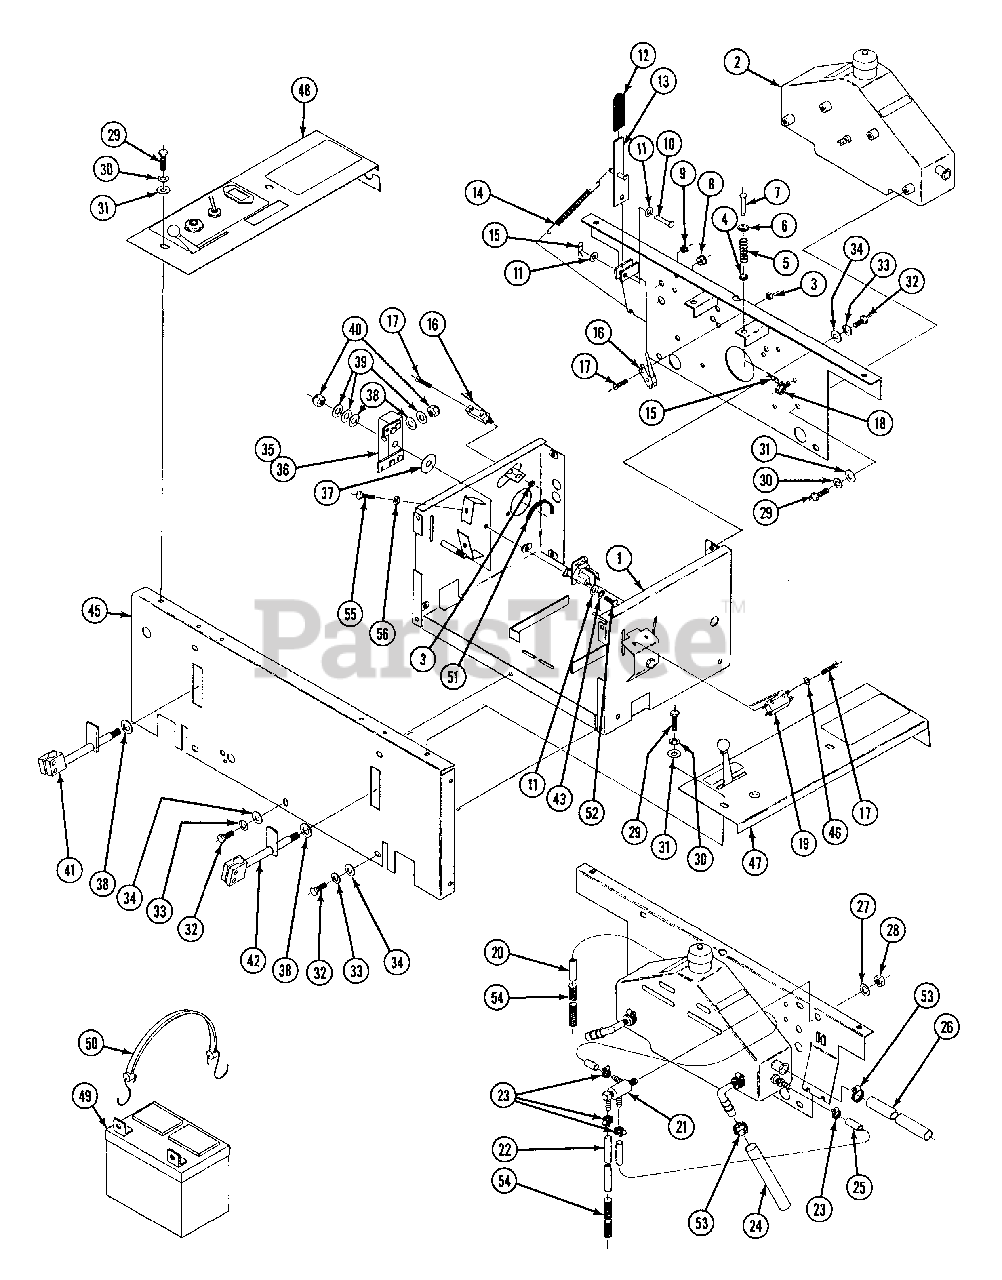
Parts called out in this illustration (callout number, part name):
1	SEAT SUPPORT BASE WELDMENT
2	OIL TANK ASSEMBLY
3	NUT, NYLOCK: 6-32
4	WASHER, NYLON: SEAT SPRING
5	SPRING, COMPRESSION: .720 OD X 2 LONG
6	WASHER, SEAT SPRING
7	PIN, CLEVIS: 5/16 X 1-3/4
8	BUSHING, PLASTIC: 1-1/2 O.D.
9	BUSHING, PLASTIC: 7/8 O.D.
10	PIN, CLEVIS: 5/16 X 1
11	FLAT WASHER: 1/4
12	GRIP, VINYL
13	BRAKE HANDLE WELDMENT
14	SPRING, EXTENSION: 3-1/2
15	COTTER RUE RING: 5/16 X 3/8 PIN
16	SWITCH, 15A SPDT HINGED LEVER
17	SCREW, PHILLIPS MACHINE: 6-32 X 1
18	CLIP, ROSEBUD: 1/2
19	SWITCH, 15 A DPDT HINGED LEVER
20	HOSE, LEFT BRAKE
21	VALVE, BRAKE ASSEMBLY
22	HOSE, RIGHT BRAKE
23	CLAMP, HOSE: 1/4
24	HOSE, INLET
25	HOSE, BRAKE RETURN
26	HOSE, RETURN
27	WASHER, INTERNAL LOCK: 5/8
28	NUT, HEX: 5/8-11
29	CAPSCREW, HX HD: 5/16-18 X 1 GR 5
30	LOCKWASHER, SPLT SPRNG: 5/16
31	FLAT WASHER: 5/16
32	CAPSCREW, HX HD: 3/8-16 X 3/4 GR 5
33	LOCKWASHER, SPLT SPRNG: 3/8
34	FLAT WASHER: 3/8
35	ROTARY MOUNT ASSEMBLY, RH
36	ROTARY MOUNT ASSEMBLY, LH
37	WASHER, NYLON SPACER: 1-1/2 OD
38	WASHER, NYLON: 1/2 ID X 1 OD
39	WASHER, STEEL: 1/2 ID
40	LOCKNUT, 1/2-20 NYLOCK
41	HANDLE CONNECTOR WELDMENT RH
42	HANDLE CONNECTOR WELDMENT LH
43	LOCKWASHER, SPLT SPRNG: 1/4
45	SEAT SUPPORT FRONT
46	LOCKWASHER, INTERNAL STAR: 6
47	FENDER CAP ASSEMBLY, LH
48	FENDER CAP ASSEMBLY, RH
49	BATTERY, 12 VOLT
50	RUBBER TIE DOWN STRAP, 12
51	TRIM, U-CHANNEL
52	CAPSCREW, HX HD: 1/4-20 X 1/2
53	CLAMP, HOSE: 3/4
54	SHEILD, CABLE
55	CAPSCREW, HX HD: 1/4-20 X 1 GR 5
56	NUT, HEX: 1/4-20
